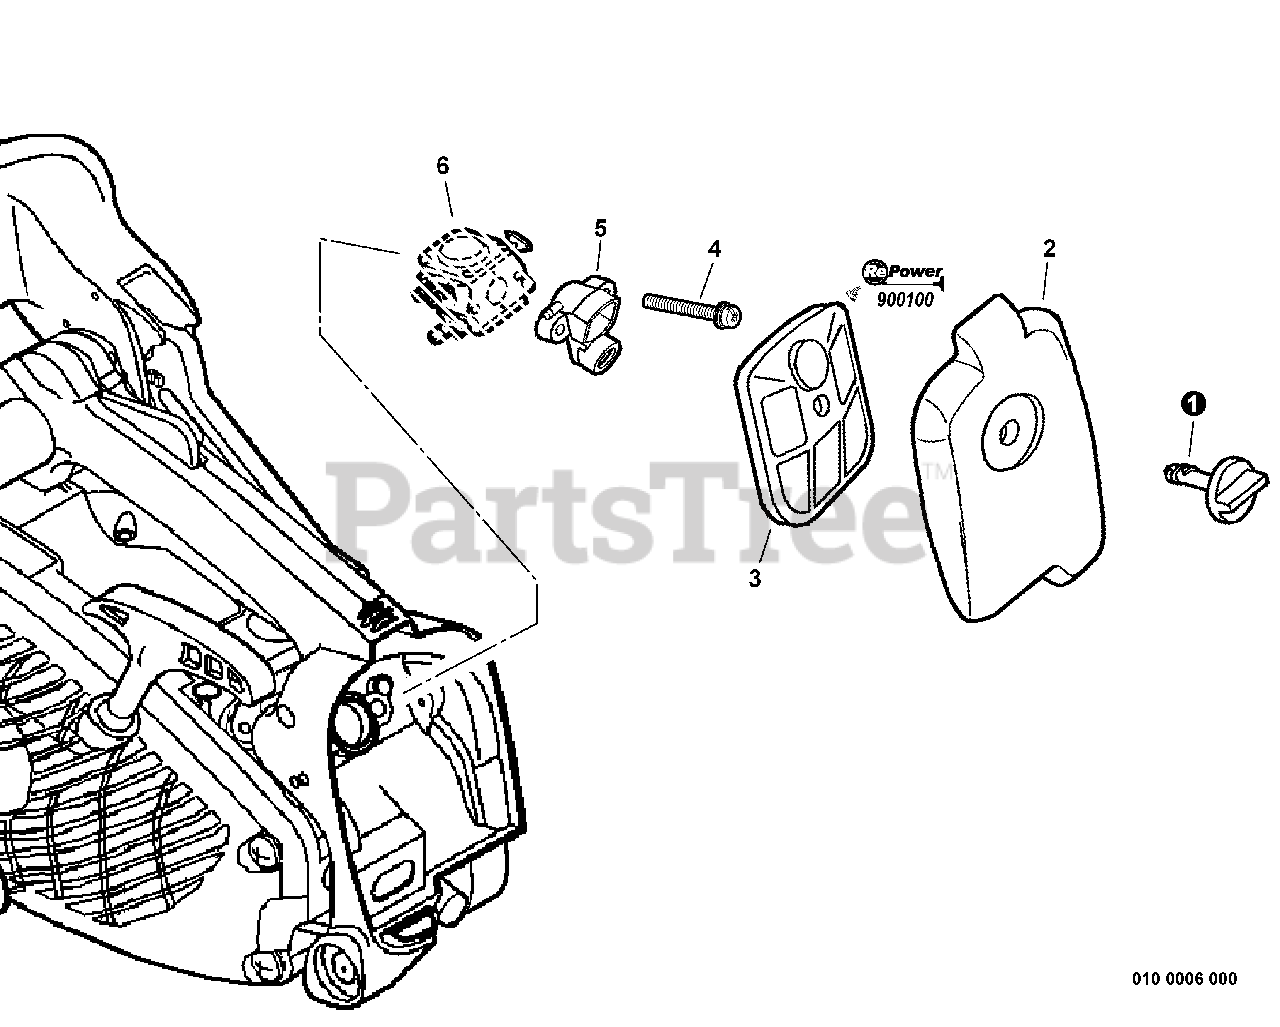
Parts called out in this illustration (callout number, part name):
1	THUMBSCREW
2	COVER, AIR FILTER
3	FILTER, AIR
4	SCREW - 5X50
5	MOUNT, AIR FILTER
6	CARBURETOR
7	RePower TUNE-UP KIT
